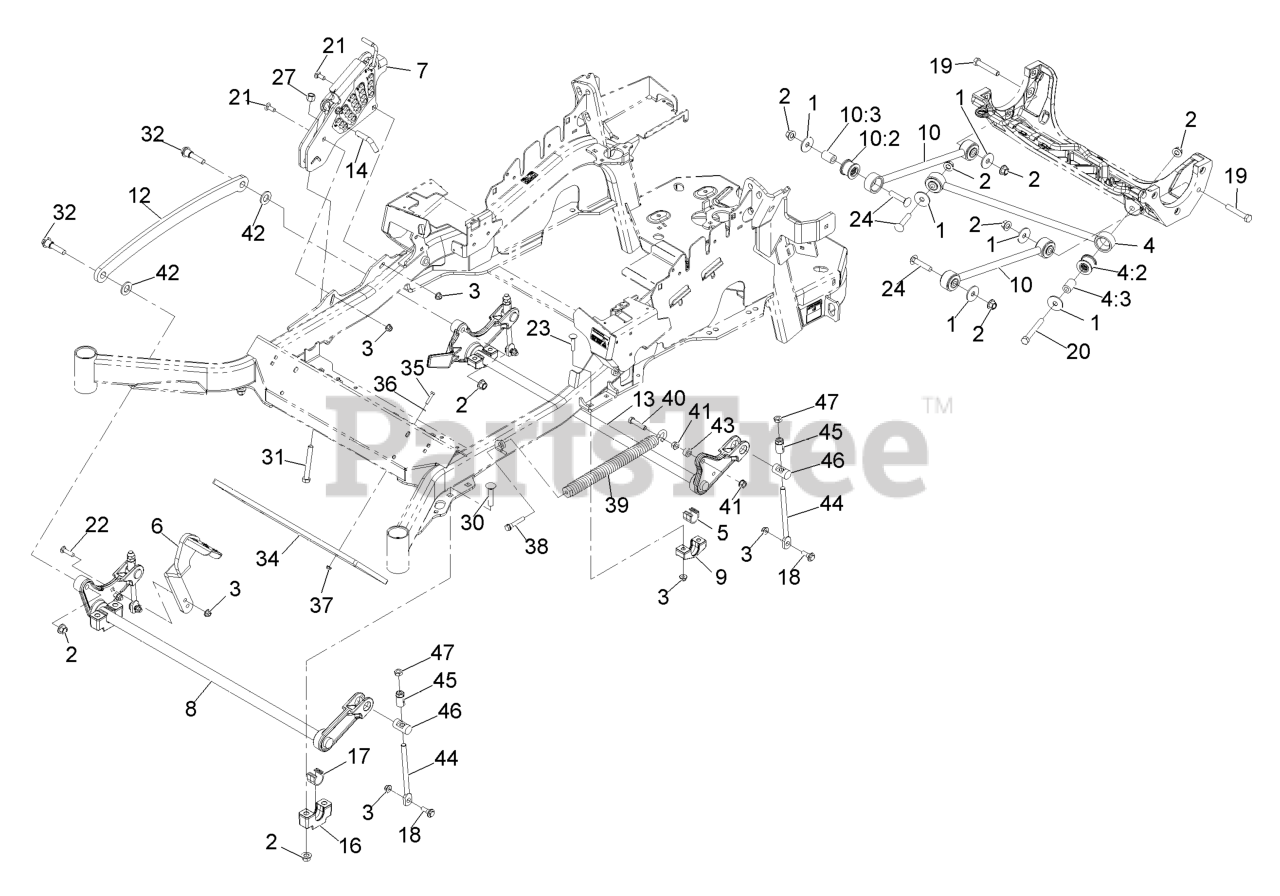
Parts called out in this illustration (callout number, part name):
1	WASHER-THRUST
2	Nut-Lock 1/2-13
3	NUT-HF, NI
4	PANHARD ROD ASM
4:2	BUSHING-SUSPENSION, RUBBER
5	BEARING-CROSS SHAFT, REAR
6	LEVER-FOOT
7	HOC ASM
10	DECK STRUT ASM
10:2	BUSHING-SUSPENSION, RUBBER
12	LINK-LIFT, DECK
13	LIFT-DECK, REAR
14	PIN-HOC
16	SUPPORT-CROSS SHAFT, BEARING
17	BEARING-CROSS SHAFT, FRON
18	SCREW-SHOULDER, HHF
19	SCREW-HH
20	SCREW-HH
21	BOLT-CARR
22	SCREW-CARR
23	SCREW-CARR
24	SCREW-CARR
27	NUT-LOCK, NI
30	Bolt-Carriage 1/2-13 X 2 1/2 Spl Neck
31	BOLT-TAP
32	SCREW-HHF, SHOULDER
34	WEIGHT,TOE BOARD
35	SCREW-HH
36	WASHER-FLAT
38	BOLT-SHOULDER
39	SPRING-EXTENSION
40	SCREW-HH
42	WASHER-FLAT
44	LINK-ADJUSTER, DECK LIFT
45	ADJUSTER-LIFT, DECK
46	TRUNNION
47	NUT-JAM
